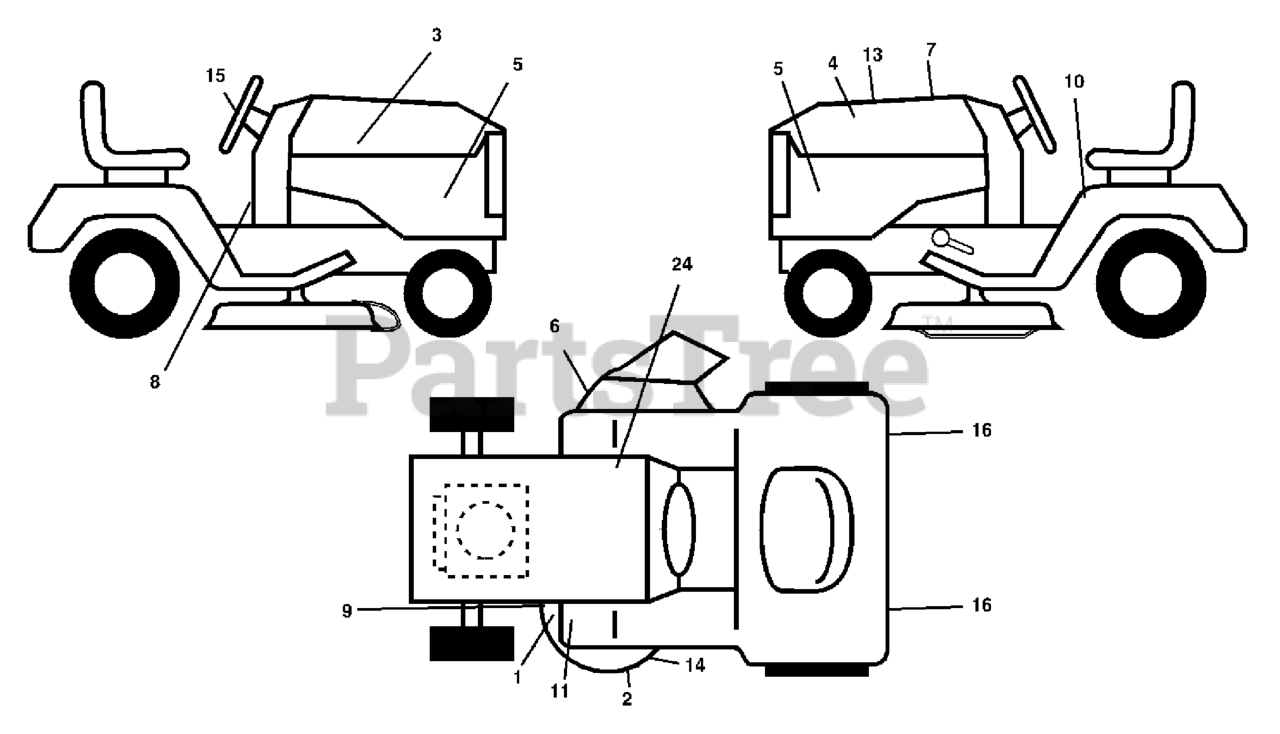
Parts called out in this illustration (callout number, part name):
1	DECAL CLUTCH/BRAKE
2	DECAL, MOWER HEAVY DUTY
5	DECAL, SIDE PANEL
6	DECAL.WARN.KEEP.HAND.AWAY
7	DECAL HOOD CUST. RESP.
8	DECAL.SADDLE.OPERATOR
9	DECAL.MOWER
10	DECAL FENDER DANGER
11	DECAL, FOOTREST
13	DECAL, REPLACEMENT
14	DECAL.SCHEMATIC.DECK
15	DECAL.STEERING.HUSQ.BLUE
16	REFLECTOR-TAIL YT
24	DECAL BTRY SYMBOLS
